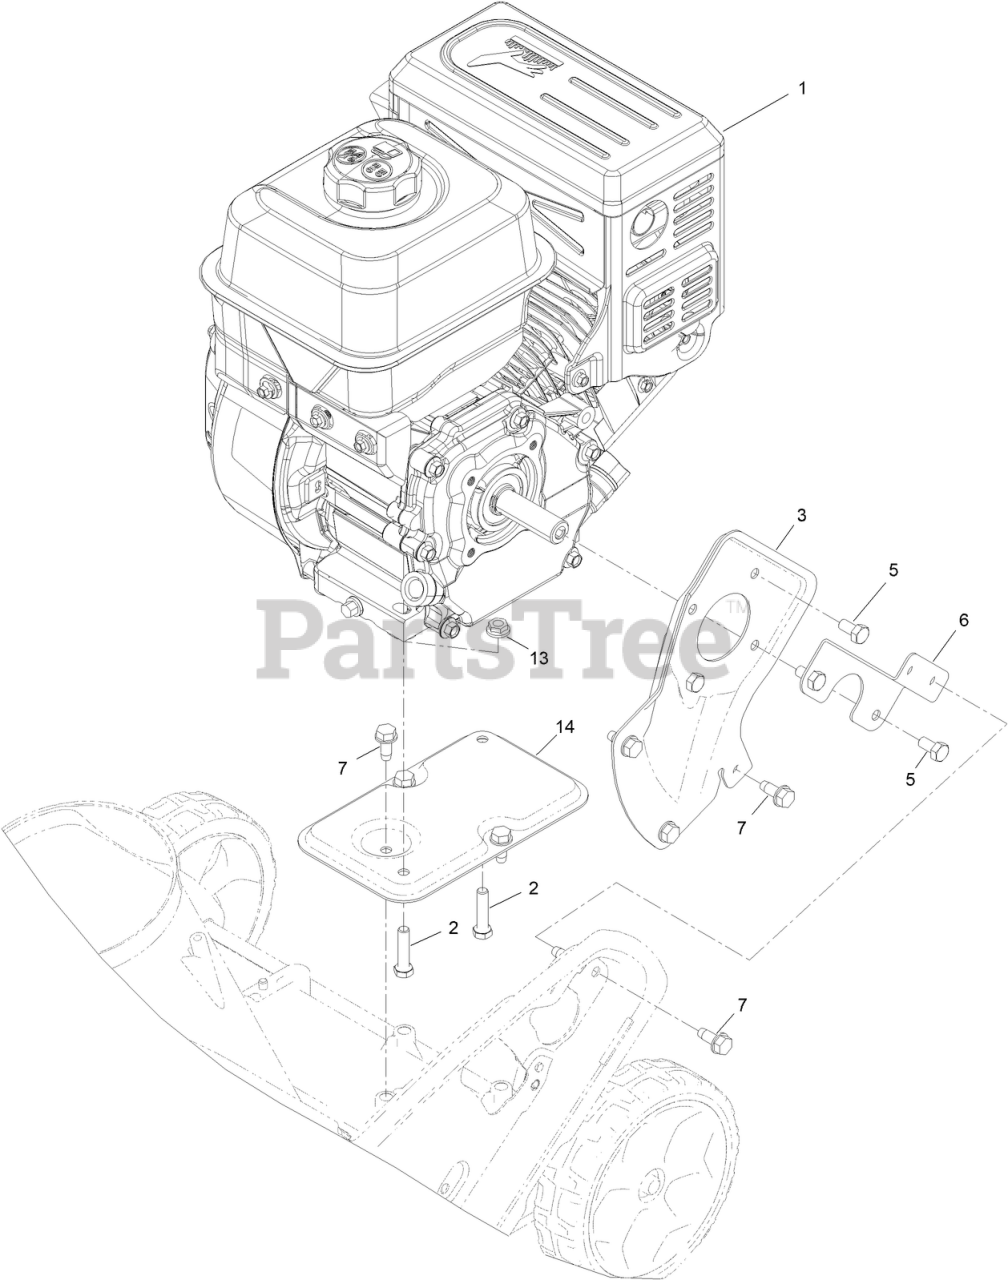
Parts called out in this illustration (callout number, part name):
1	ENGINE-G210FDS-4
2	SCREW-HH
3	PLATE-ENGINE, PTO
5	BOLT
6	SUPPORT-ENGINE, SIDE
7	SCREW-THD ROLL, HWH
13	NUT-HF
14	SUPPORT-ENGINE
